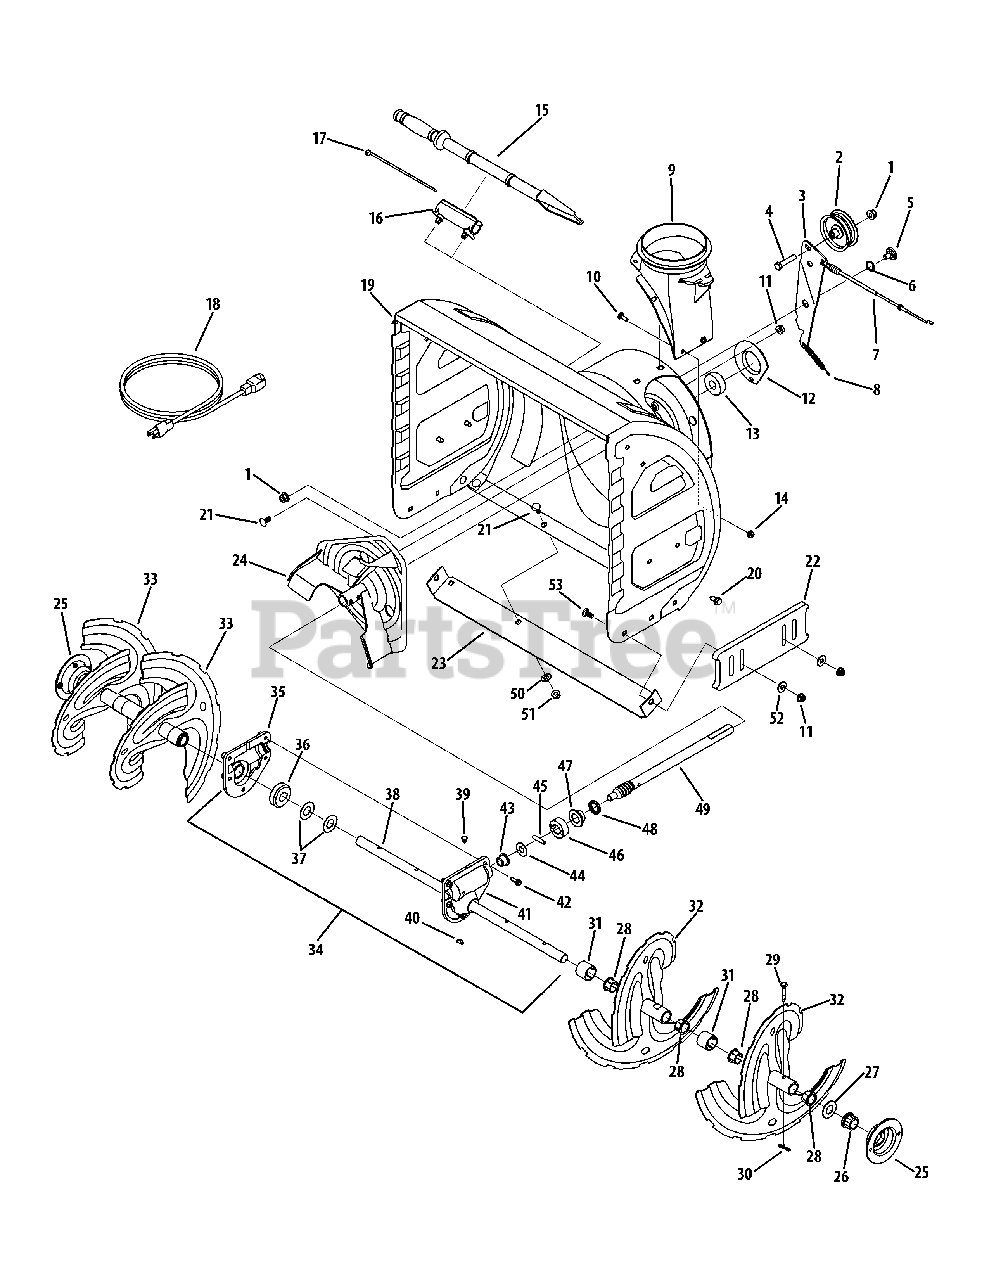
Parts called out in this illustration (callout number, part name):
1	Flange Lock Nut, 3/8-16
2	Idler Pulley
3	Auger Idler Bracket w/ Brake
4	Hex Bolt, 3/8-16 x 1.75
5	Shoulder Screw, .625 x .17 x 3/8-16
6	Wave Washer, .625 x .885 x .015
7	Clutch Cable
8	Extension Spring, .38 OD x 3.6
9	Chute Adapter, 5.0
10	Carriage Screw, 1/4-20 x .75
11	Flange Lock Nut, 5/16-18
12	Bearing Housing
13	Ball Bearing, .75 ID x 1.85 OD
14	Flange Lock Nut, 1/4-20
15	Cleanout Tool
16	Cleanout Tool Mount
17	Cable Tie, 3/16 x .05 x 7.4
18	Extension Cord, 3-Prong
19	Auger Housing, 26"
20	Hex Washer Screw, 5/16-18 x .750
21	Carriage Bolt, 5/16-18 x .750
22	Deluxe Polymer Skid Shoe
23	Stainless Steel Shave Plate, 26"
24	Impeler Assembly
25	Bearing Housing
26	Hex Flange Bearing
27	Flat Washer, .76 x 1.49 x .06
28	Flange Bushing .800 ID x .910 OD
30	Bow-Tie Cotter Pin
31	Spacer, 1.25 OD x .75 ID x 1.00
32	Spiral Assembly, LH
33	Spiral Assembly, RH
34	Gearbox Assembly, 26"
35	Housing Assembly, RH
36	Worm Gear, 2OT
37	Flat Washer, .760 ID x 1.50 OD
38	Auger Axle, 26"
39	Plug, 1/4 x .437
40	Hi-Pro Key, 3/16 x 5/8
41	Housing Assembly, LH
42	Hex Washer Screw, 1/4-20 x .750
43	Flange Bearing, .50 ID x .75 OD x .59
44	Flat Washer, .51 x 1.12 x .06
45	Dowel Pin, .25 OD x 1.25
46	Thrust Collar, .756 ID x .600
47	Flng. Bearing, .75 ID x 1.00 OD x .59
48	Oil Seal, .75 x 1.131 x .188
49	Worm Shaft, .75 OD
50	Bell Washer, .340 x .872 x .060
51	Hex Nut, 5/16-18
52	Flat Washer, .349 x .879 x .063
53	Carriage Screw, 5/16-18 x 1.00
